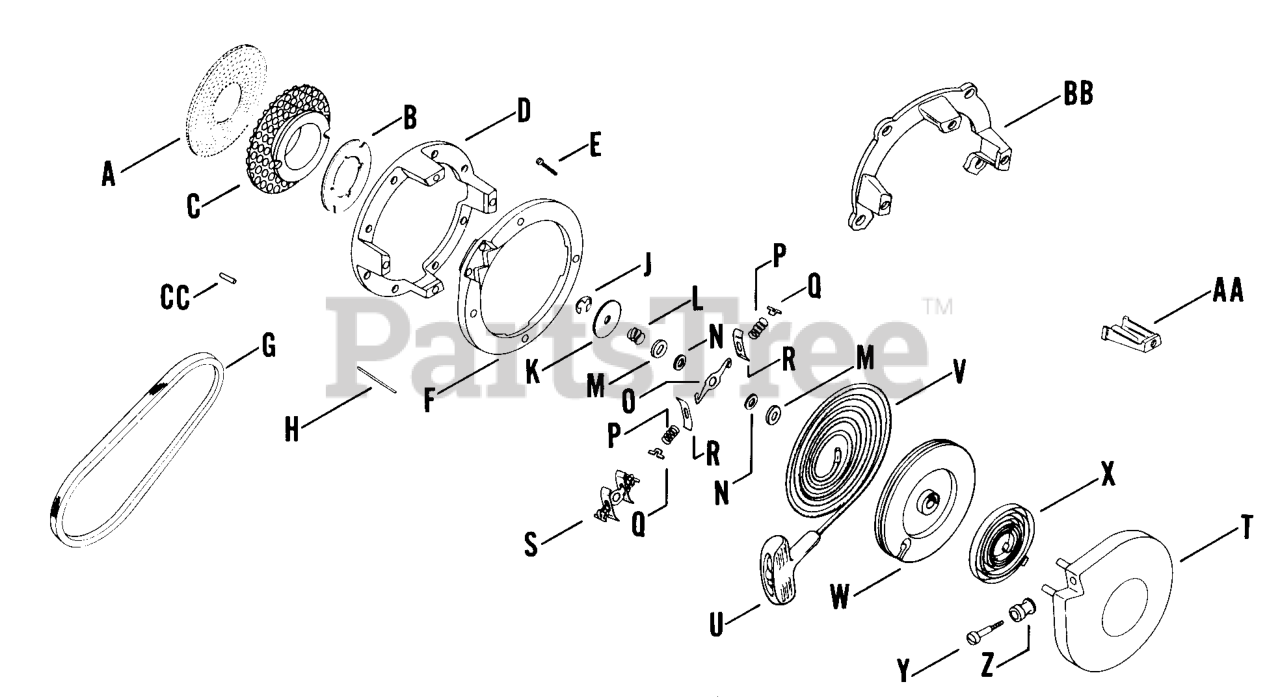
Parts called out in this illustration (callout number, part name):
E	SCREW - DISCONTINUED
F	FLANGE - DISCONTINUED
J	RING - DISCONTINUED
K	WASHER - DISCONTINUED
L	SPRING - DISCONTINUED
N	WASHER - DISCONTINUED
S	SHOE - DISCONTINUED
U	HANDLE - USE 25 166 01
V	CORD - DISCONTINUED
W	ROTOR - DISCONTINUED
X	SPRING - DISCONTINUED
Y	SCREW - DISCONTINUED
